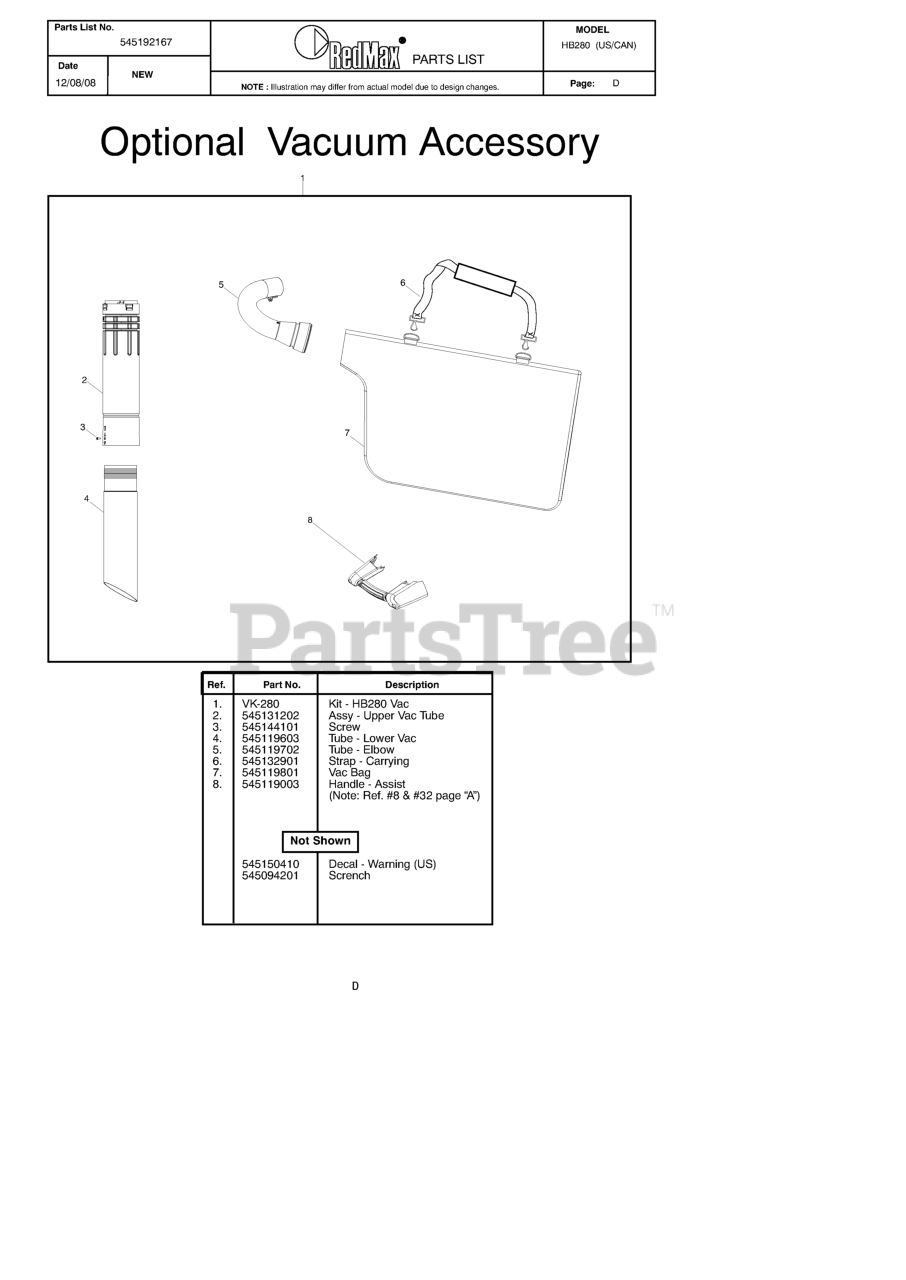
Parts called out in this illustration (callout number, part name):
1	KIT-HB280VAC
2	ASSY - UPPER VAC TUBE
4	TUBE - LOWER VAC
5	TUBE - ELBOW
6	STRAP - CARRYING
7	VAC BAG
8	HANDLE - ASSIST
NI	DECAL - WARNING (US)
NI	SCHRENCH
